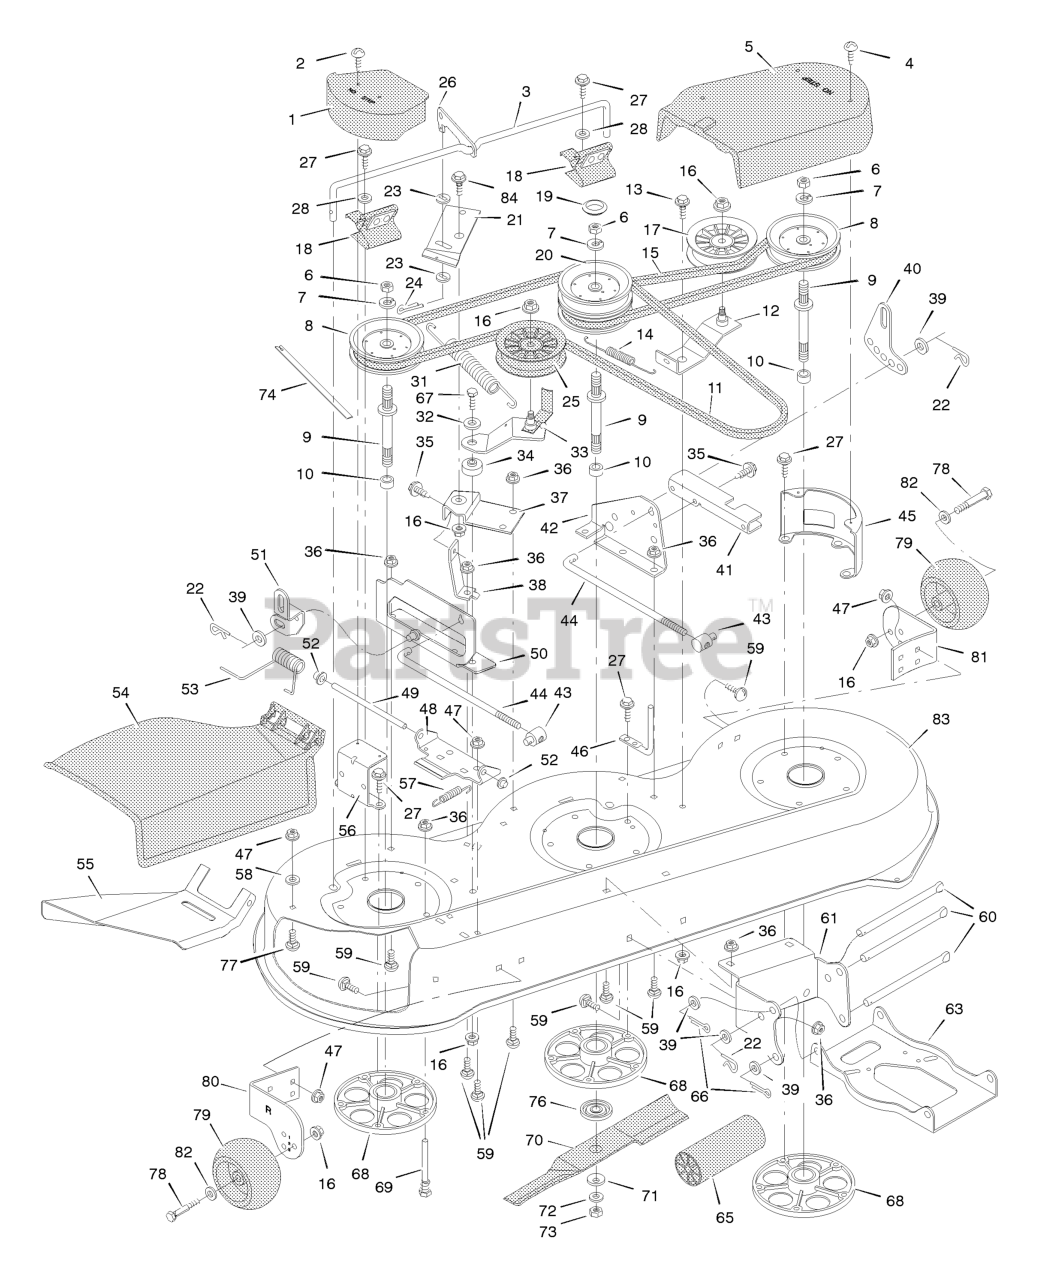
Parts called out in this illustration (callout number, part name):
1	Cover, Pulley
3	Rod, Brake
5	Cover, Left Pulley
6	Nut, Hex
7	Lockwasher
9	Jackshaft
10	Spacer, Bearing
11	Belt, Primary Mower Drive
12	Bracket, Idler
13	Bolt, Shoulder
14	Spring, Extension
15	Belt, Secondary Mower Drive
16	Locknut
17	Pulley, Idler
18	Spring Assembly, Brake
20	Pulley, Stack
21	Bracket, Pivot
22	Pin, Hair
24	Pin, Cotter
25	Pulley, Idler
26	Link, Brake
27	Screw
31	Spring, Extension
33	Bracket, Idler
34	Bushing
36	Nut, Hex
37	Support, Pivot
38	Strut, Pivot
40	Plate, Adjuster
41	Channel, Left Cover
42	Bracket Assembly, Lifter
43	NUT, Adjusting, 1/2-13
44	Rod, Adjuster
45	Bracket, Left Cover
46	Guide, Belt
47	Locknut
48	Bracket, Hinge
49	Rod, Deflector
50	Bracket Assembly, Lifter
51	Link, Suspension
52	Push- On Cap
53	Spring, Torsion
54	Deflector
55	Deflector, Inside
56	Bracket, Cover
57	Spring, Extension
59	Bolt, Carriage
60	Rod, Hanger
61	Bracket, Front Hanger
63	Hanger, Front
66	Pin, Cotter
67	Bolt, Hex
68	Housing, Mandrel
69	Guide, Belt
70	Blade (3 required)
71	Washer, Belleville
73	Nut, Hex
74	Indicator, Plastic
76	Adapter, Blade
77	Bolt, Carriage
78	BOLT, Gauge Wheel
79	Wheel, Gauge
80	Bracket, Right Gauge Wheel
81	Bracket, Left Gauge Wheel
82	Washer
83	Housing, Mower
84	Bolt, Shoulder
